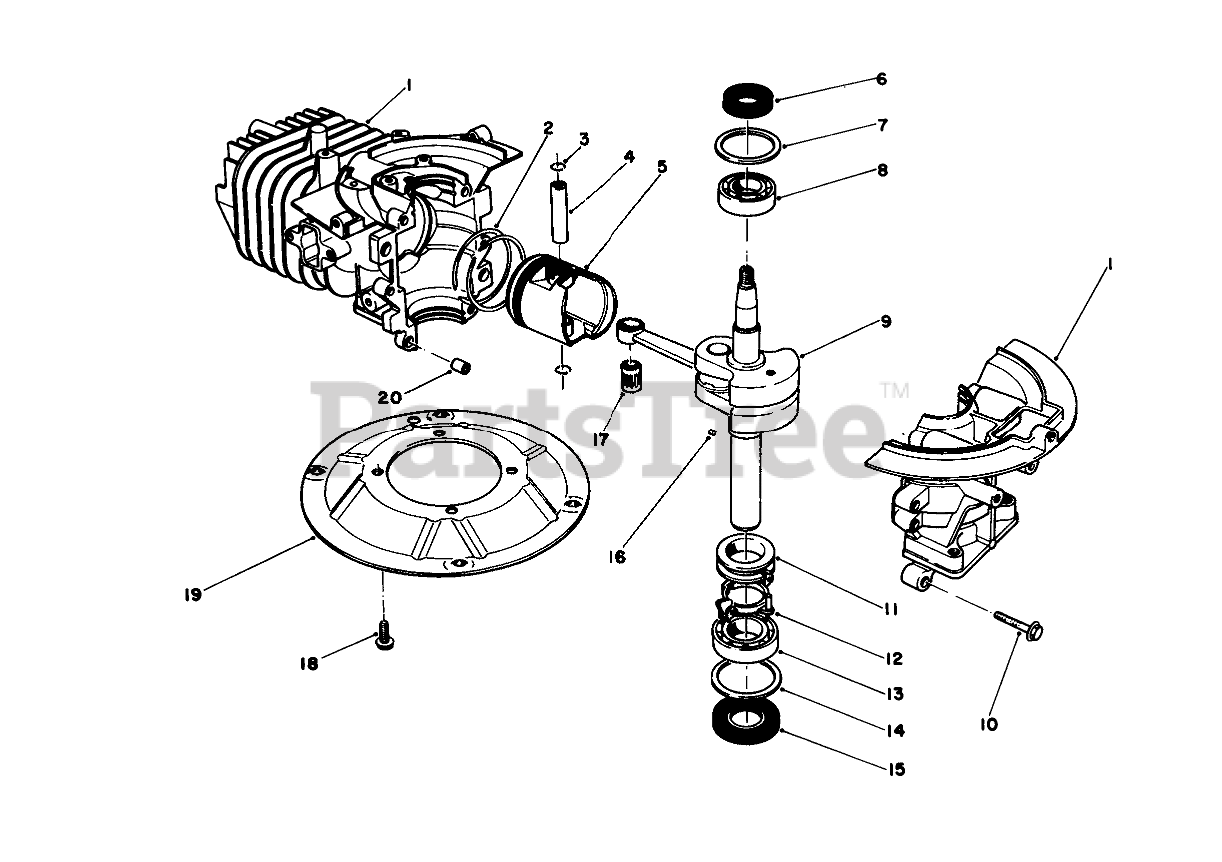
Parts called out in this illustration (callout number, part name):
1	CRANKCASE
2	RING SET
4	PIN-PISTON
5	Piston
6	OIL SEAL
7	GASKET
8	BEARING-UPPER
9	Pin-Wrist
11	SPACER
12	BRACKET
13	LOWER BRG
14	WASHER-LOWER
15	SEAL-OIL
17	BEARING
19	PLATE-MOUNTING
